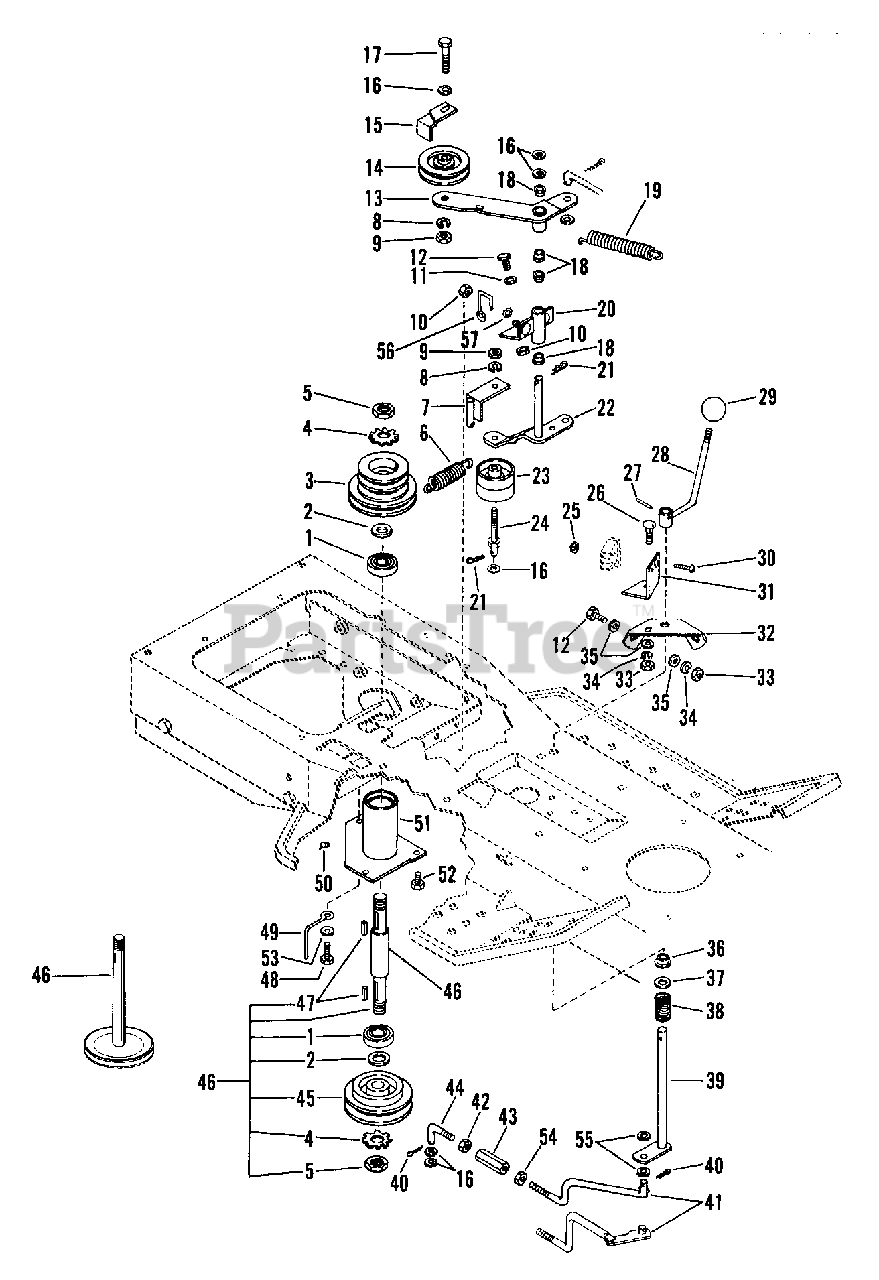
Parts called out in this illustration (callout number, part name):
1	BRG-BALL .750X1.781X.61
2	WSHR-FL-STL .755X1.250X.125
3	TRIPLE GROOVE PULLEY
3	DOUBLE GROOVE SHEAVE
4	STAR WASHER
5	NUT-JAM .75-10 PL
6	SG-TENS .112X.89X5.28 WLD 56
7	BRACKET
8	WSHR-LK .375X.115 HVY PL
9	NUT-HEX .375-16
10	NUT-LK .312-18 GR A PL
11	WSHR-FL-STL.312X.734X.065PL
12	BLT-HEX .31-18X.75 PL GR5
13	IDLER ARM
14	IDLER-V 3.06 X .38
15	BELT RETAINER
16	WSHR-FL-STL.406X.812X.065PL
17	BLT-HEX .38-16X1.75 PL GR2
18	BSHG-FLG .372X.500X.312X.625NY
19	SG-TENS .105X.812X3.88 WLD 15
20	IDLER PIVOT
21	PIN-HAIR INT .08X.18X1.18
22	IDLER ARM
23	IDLER-FLAT 2.25 X .38
24	BLT-HEX .38-16X1.75 PL GR2
24	IDLER MTG BOLT
25	NUT-KEPS 10-24 PL
26	BLT-RDHDSQNK .31-18X.75 GR5 PL
27	PIN-ROLL .188X1.25
28	P T O HANDLE
29	SHIFT BALL
30	SCR-MCH 10-24X1.00 SLRH PL
31	SWITCH BRACKET
32	BRACKET
33	NUT-HEX .312-18
34	WSHR-LK .312X.097 PL HVY
35	WSHR-FL-STL .323X.625X.062 PL
36	BSHG-FLG.500X.625X.312X.750NY
37	WSHR-FL-STL .531X1.062X.095 PL
38	SG-COMP .080X.85X1.44
39	PTO LEVER
40	PIN-COTR .12X1.0 PL
41	IDLER LINK
42	NUT-JAM .375-16 PL
42	NUT-HEX .375-16
43	NUT-CUPLG .375-16 PL
43	NUT-CUPLG RH & LH THD .37-16PL
44	IDLER ADJUSTOR LINK
45	SHEAVE-JACKSHAFT
46	JACKSHAFT
46	JACKSHAFT ASSEMBLY
47	KEY-SQ .188X1.0X.188 SAE 8630
48	BLT-HEX .31-18X1.00 PL GR 2
49	BELT FINGER
50	HYDRAULIC LUBRICATION FITTING
51	SPINDLE HOUSING
52	BLT-HEX .31-18X1.50 PL GR2
53	WSHR-FL-STL .328X1.0X.094 PL
54	NUT LH THD .375-16 GR 2 PL
55	WSHR-FL-STL .382X.812X.023 PL
56	BELT FINGER
57	WSHR-LK-EXT .313X.030 PL
